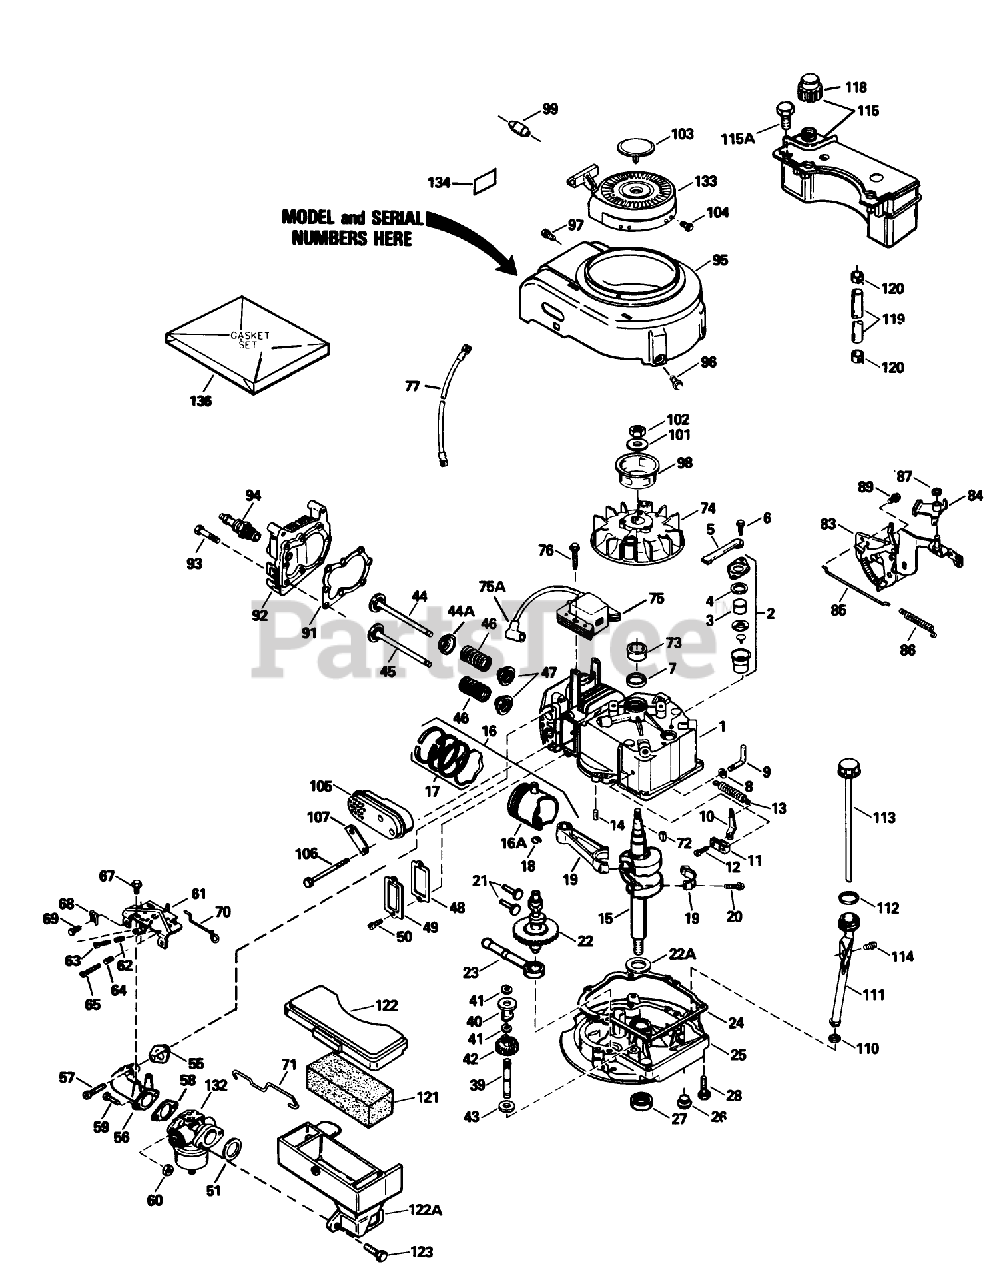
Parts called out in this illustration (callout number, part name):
1	Cylinder Assembly (Incl. Ref. #7 14)
2	Breather Assy. (Incl. Ref. #46 thru 51)
3	Element-Breather
4	Gasket-Breather
5	Tube, Breaker
6	Screw (10-24 x 9/16)
7	Seal-Oil
8	Washer-Flat
9	Rod, Governor (Incl. No. 36)
10	Governor Lever
11	Clamp-Lever, Governor
12	Screw
13	Spring Governor
14	Pin-Dowel
15	Crankshaft Assy.
16	Piston-Pin Ring Assy. (Std.)(Incl. Ref. #16A, 17 18)
16	Piston-Pin Ring Assembly (.010 oversize)(Incl. Ref. #16A, 17 18)
16	Piston, Pin Ring Assy. (.020 Oversize)(Incl. Ref. #13A, 14, 15)
16A	Piston Pin Assy. (Std.)(Incl. Ref. #14)
16A	Piston Pin Assembly (.010 oversize)(Incl. Ref. #18)
16A	Piston Pin Assy. (.020 Oversize) (Incl. Ref. #14)
17	Ring Set-Piston (Std.)
17	Ring Set, Piston(.0100versize)
17	Ring Set (.020" OS)
18	Ring-Retaining, Piston Pin
19	Rod Assembly, Connecting (Incl. Nos. 17 18)
20	Bolt-Rod, Connecting
21	Lifter-Valve
22	Camshaft(Mech.Comp. Release)
22A	Washer-Thrust
23	Oil Pump ASM
24	Gasket
25	Flange, Mounting (Incl. Ref. #26, 27 39)
26	Plug Oil Drain
27	Seal-Oil
28	Screw (1/4-20 x 1-1/4)
39	Shaft-Governor
40	Spool-Governor
41	Ring-Retaining
42	Governor Gear ASM
43	Washer-Flat
44	Valve, Intake (Std.) (Incl. Ref. #40)
44	Valve, Intake (1/32" oversize)(Incl. No. 40)
44A	Seal Assy., Intake
45	Valve, Exhaust (Std.)(Incl. No. 40)
45	Valve, Intake (1/32" oversize)(Incl. No. 40)
46	Spring-Valve
47	Cap-Valve, Spring
48	Gasket-Breather
49	Cover-Valve
50	Screw
51	Gasket-Cleaner, Air
55	Gasket-Intake
56	Pipe-Intake (Incl. Ref. #59)
57	Screw (1/4-20 x 1)
58	Gasket
60	Nut and Lock Washer (1/4-28)
61	Control Assy.-Remote Speed (Incl. Ref. #69 thru 72 76)
62	61709/GIL1515A/95-5
63	Screw
64	Spring-Compression
65	Screw
67	Screw (10-24 x 9/16)
68	Conduit
69	Screw (10-32 x 3/8)
70	2035A67 ADD.ASSEMBL
71	Link-Throttle
72	Key-Flywheel
73	Spacer
74	Flywheel
75	Solid State
75A	Cover-Spark Plug
76	Screw
77	Ground Wire
83	Bracket-S.E. Brake
84	Lever-Brake
85	Link-Control
86	Spring-Extension
87	Ring-Retaining
89	Screw (1/4-20 x 3/8)
91	63573 GIL 42 SNWTHW
92	Head-Cylinder
93	Screw (5/16-18x1-1/2)
94	Spark Plug-Resistor (R J19 L M)
95	Housing-Blower
96	Screw (1/4-20 x 1/2)
97	Screw (10-24 x 9/16)
98	Hub-Starter
99	Retainer-Starter Rope
101	Washer-Belleville
102	Nut-Flywheel
103	Plug Starter
104	Screw, Hex Hd.
105	Muffler
106	Screw
107	Plate-Lock
110	Gasket
111	Oil Fill Tube
112	O-Ring
113	Dipstick
114	Screw (10-32 x 1/2)
115	Tank Assembly-Fuel (Incl. Ref. #102)
115A	Screw (10-32 x 35/64)
118	Cap-Fuel
119	Line-Fuel
120	Clamp-Line, Fuel
121	Filter-Air Cleaner
122	Cover-Air Cleaner
122A	Body Air cleaner
123	Screw
132	Carburetor (Incl. Ref. #58)
133	Starter-Rewind
134	Decal-Primer
136	Gasket Set
